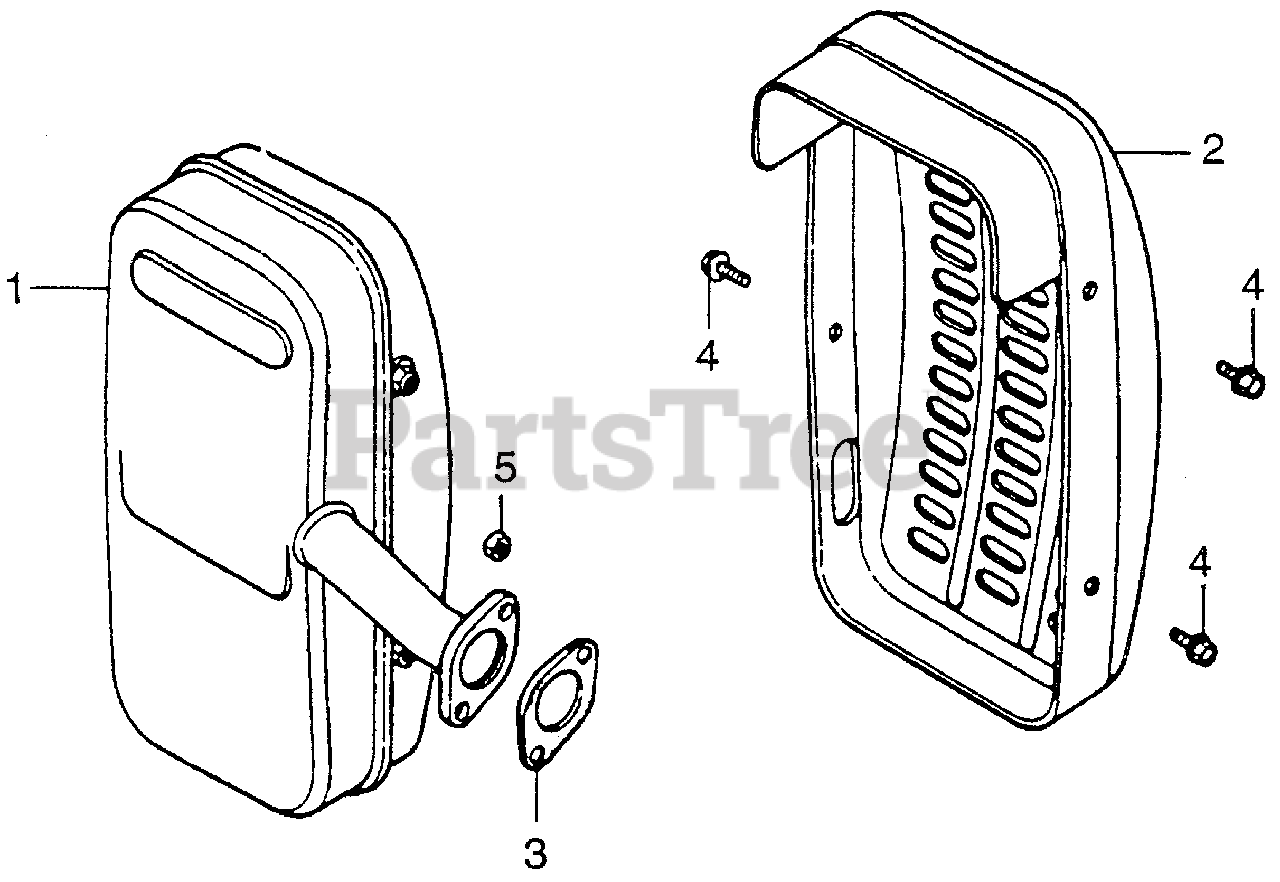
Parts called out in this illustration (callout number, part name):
1	MUFFLER (NOT AVAILABLE)
2	PROTECTOR, MUFFLER
3	GASKET, MUFFLER
4	BOLT, HEX. (6X6)
5	NUT, HEX. (6MM)
